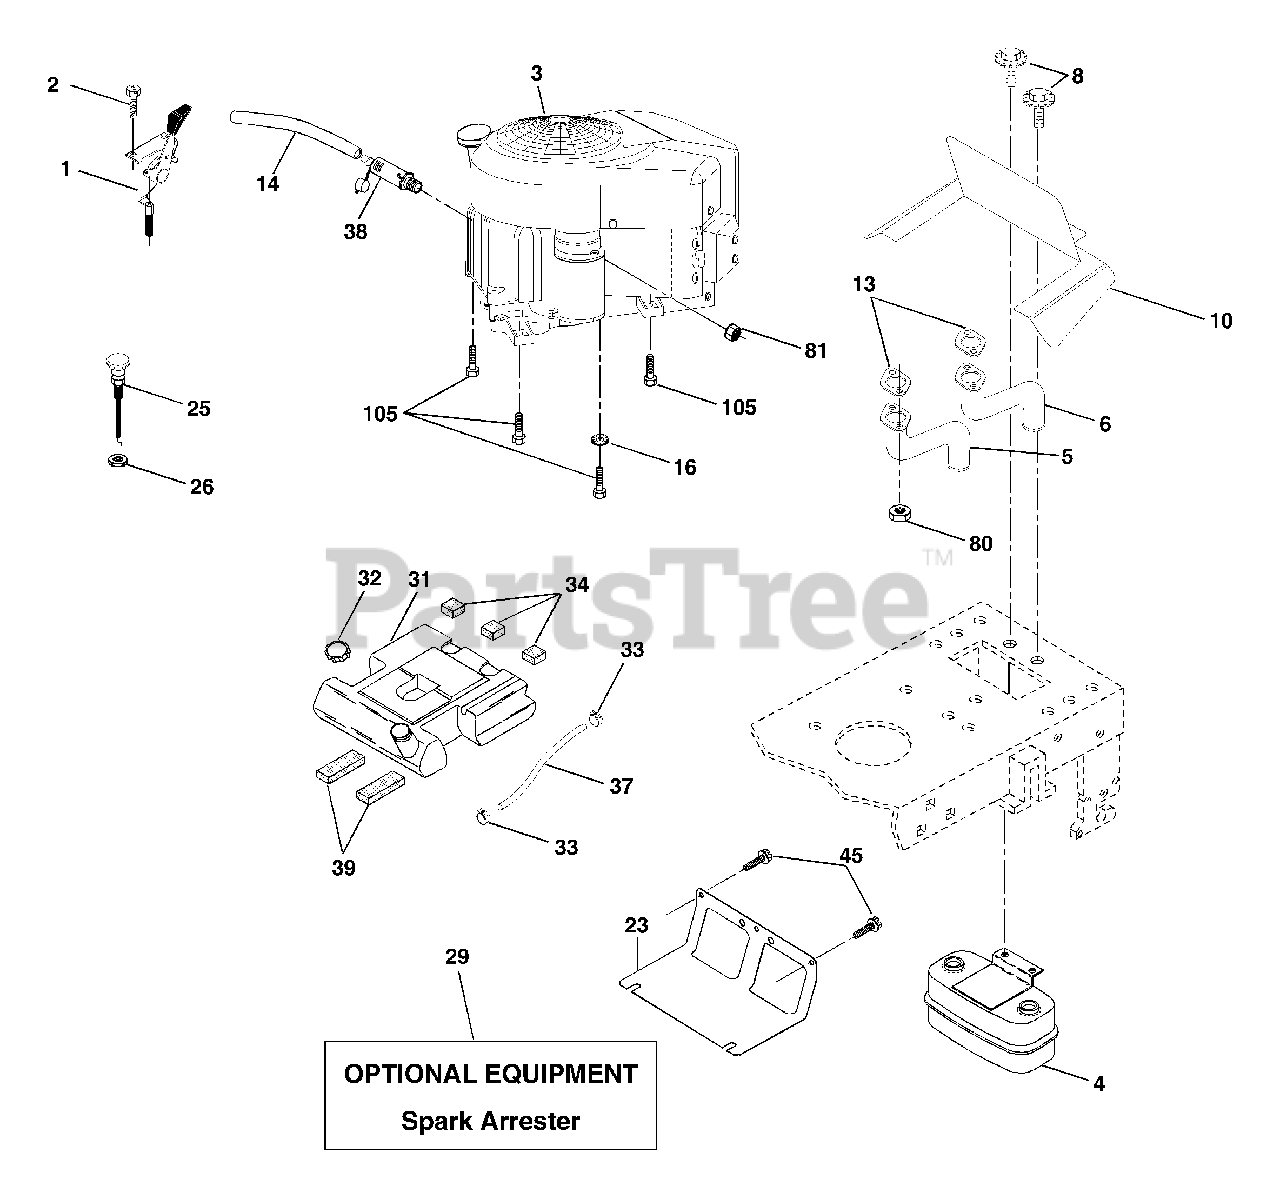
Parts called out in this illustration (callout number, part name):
1	Control Throt Flg
2	Screw Hex Thd Cut 1/4-20x5/8 T
3	Engine
4	Muffler Asm Twin Lo-Tone
5	Exhaust Tube
6	Exhaust Tube
8	Bolt 5/16-18unc x 3/4 W/Sems
10	Shield Browning
13	Gasket Muffler
14	Tube Drain Oil Easy
16	Washer Lock Ext Tooth 3/8
23	Shield Browning
25	Choke Control
26	Nut, Keps 3/8-24 Unf
29	Kit Spark Arrestor (Flat Scrn)
31	Tank Fuel 3 50 Rear
32	Cap Asm Fuel Top N/Lany Vented
33	Clamp Hose Blk
34	Pad, Spacer
37	Line Fuel
38	Plug Drain Oil Easy
39	Pad, Idler
45	Screw Hexwsh Thdr 3/8-16 x 3/4
80	Nut Flange M8-1.25
81	Nut Keps Hex 1/4-20 Unc
105	Screw 3/8-16 x 1
